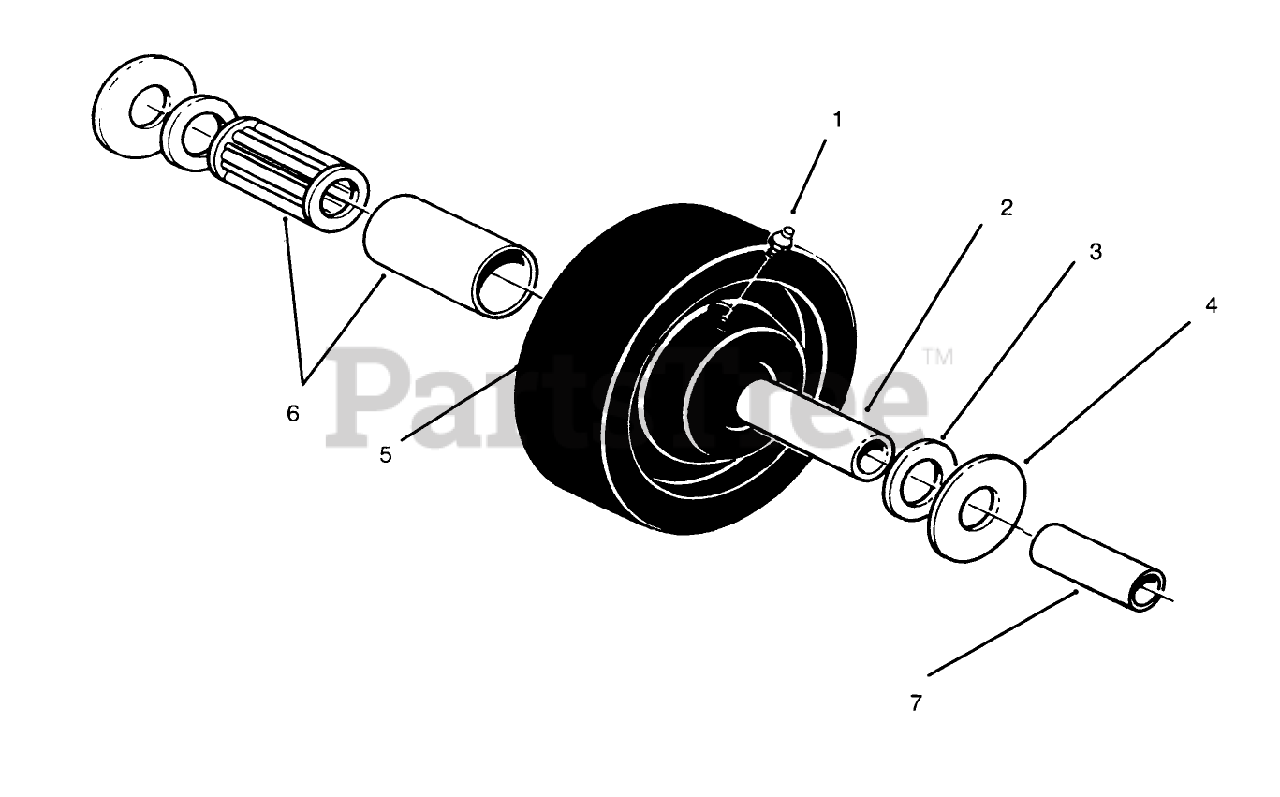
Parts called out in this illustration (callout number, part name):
1	FITTING-GREASE
2	SPANNER BUSHING
3	BEARING RETAINER
4	THRUST WASHER
5	WHEEL
6	ROLLER BEARING
